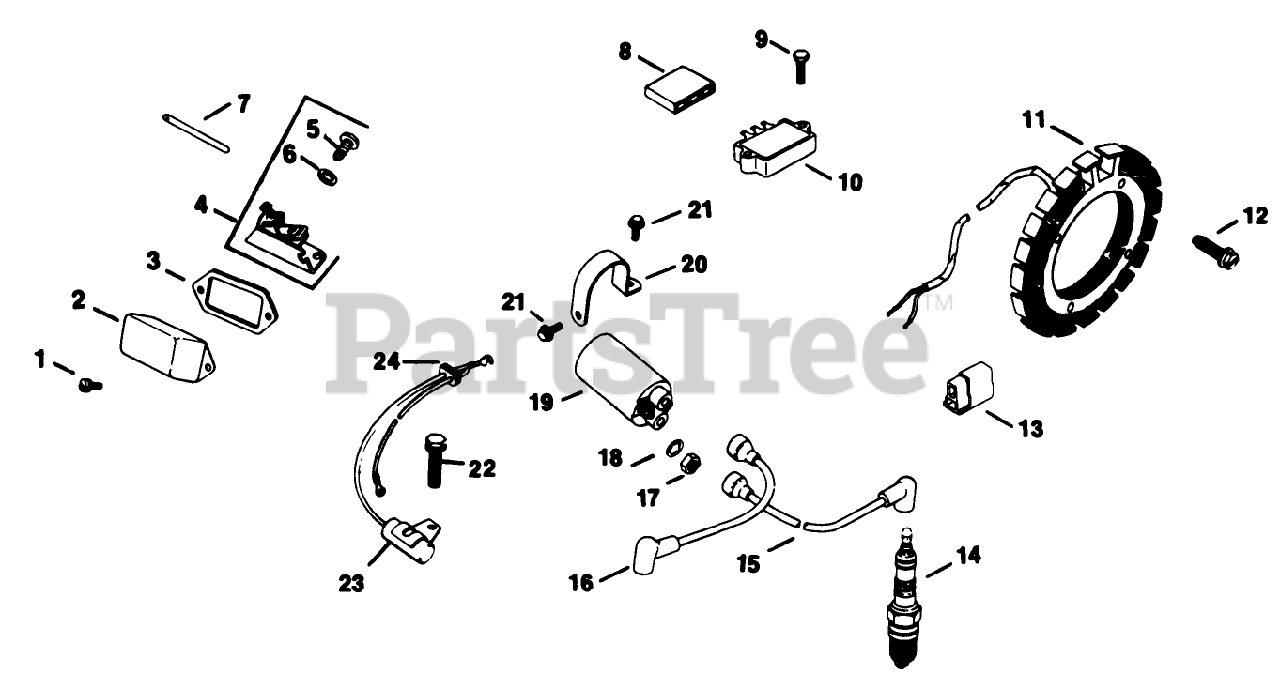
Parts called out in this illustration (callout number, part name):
1	Screw,
2	Cover-Breaker
3	Gasket-Cover
4	Breaker
5	Screw
6	Washer Plain
7	Rod-Breaker Push
8	Connector
9	Screw-H.C.
10	Regulator
11	Stator
12	Screw
13	Connector
14	SparkPlug
15	Lead-Hi-Tension 19"
16	Lead-Hi-Tension 11"
17	Nut-Hex
18	Washer
19	Coil-Ignition
20	Strap-Coil
21	Screw
22	Screw
23	Condenser
24	Grommet
